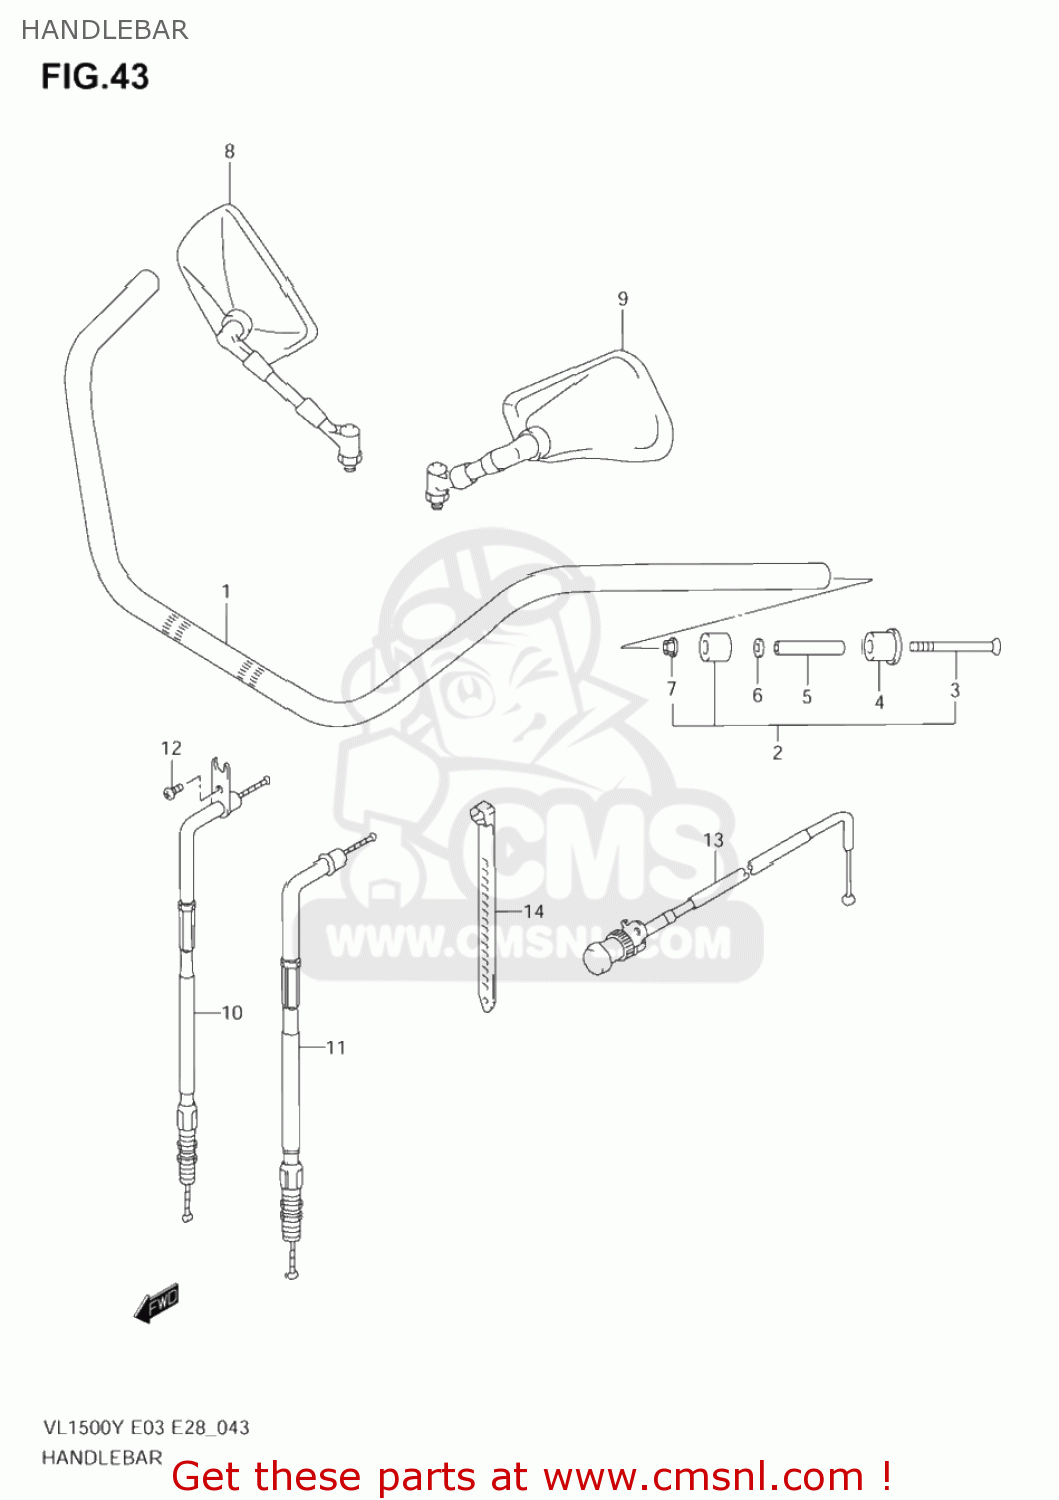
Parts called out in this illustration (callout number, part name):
1	HANDLEBAR
2	BALANCER SET,HANDLEBAR
3	SCREW(6X127)
4	EXPANDER,HANDLE BALANCER NO.2
5	SPACER,EXPANDER
6	WASHER(6.5X18X2)
7	NUT
8	MIRROR ASSY,RE
9	MIRROR ASSY,RE
10	CABLE ASSEMBLY,THROTTLE NO
11	CABLE ASSEMBLY,THROTTLE NO
12	SCREW
13	CABLE ASSY,STARTER
14	CLAMP(L:125)
